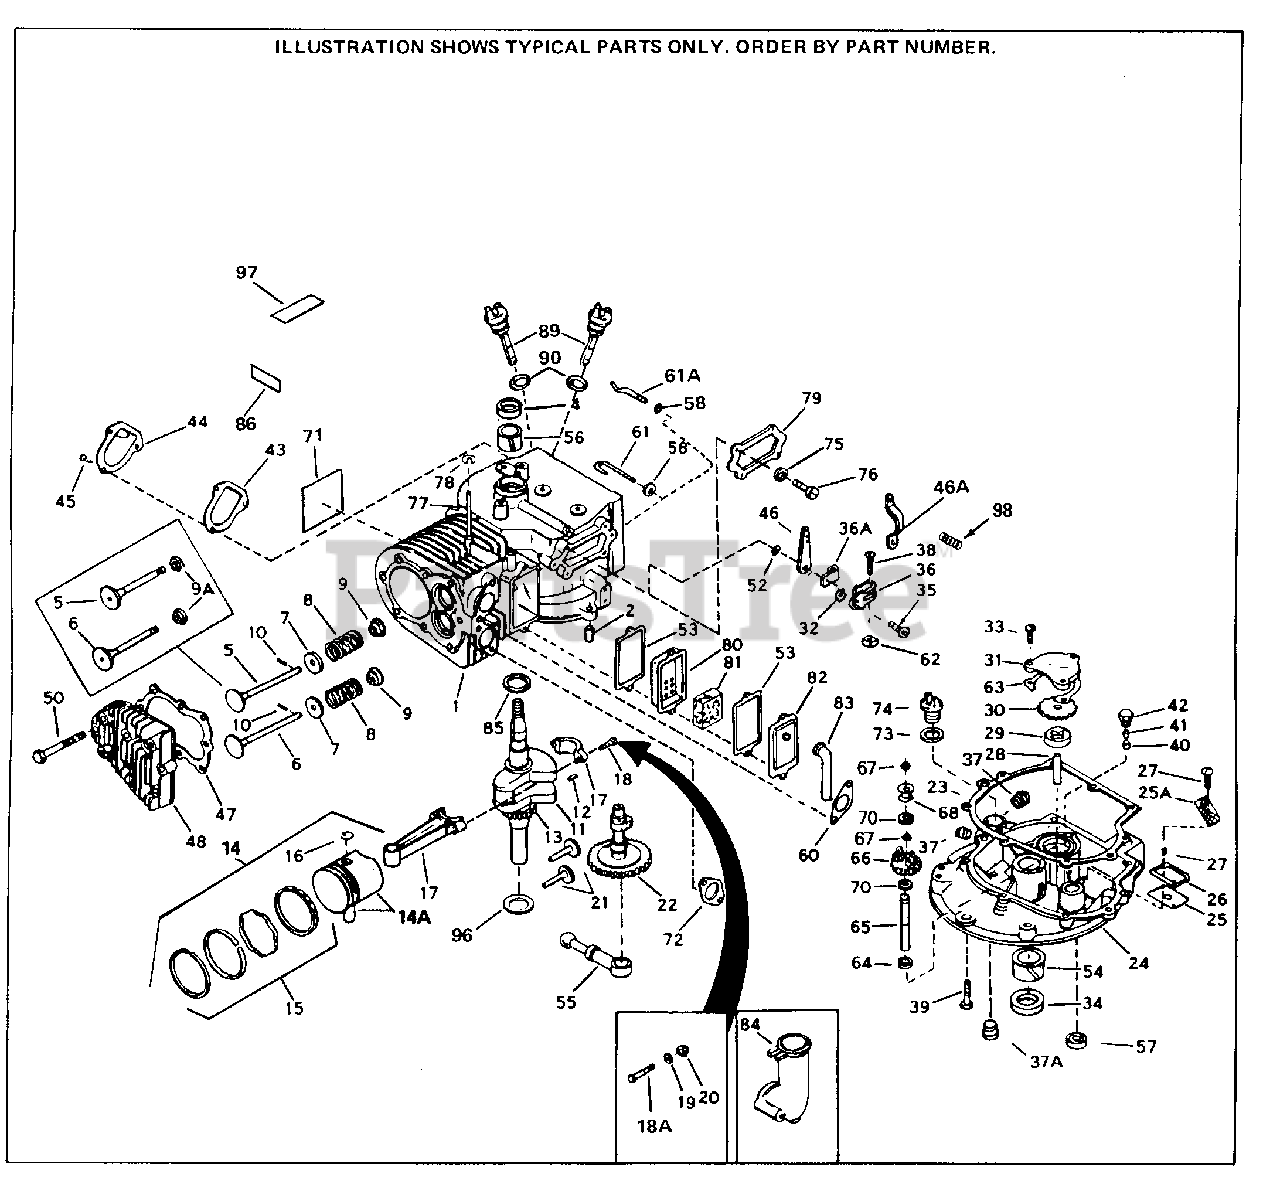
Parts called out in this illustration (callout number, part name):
1	"Cylinder (Incl. 2,4,5,9A,43,44,45,86) (2-5/8")
2	Dowel Pin
4	Seal, Oil
5	Exhaust Valve (Std.)(Incl. 151)
5	Exhaust Valve (1/32" OS) (Incl. 151)
6	Exhaust Valve (Std) (Incl. 9A)
6	Exhaust Valve (1/32" OS) (Incl. 9A)
7	Valve Spring Cap
8	Valve Spring
9	Cap, Lower valve spring (1/32" OS)
9	Cap, Lower valve spring
10	Pin, Valve spring retaining
11	Crankshaft
12	Pin, Crankshaft gear only)
13	Crankshaft Gear Early production only
14	Piston, Pin & Ring Set (Std) 2-5/8"Bo re
14	Piston, Pin & Ring Set (.010" OS)
14	Piston, Pin & Ring Set (.020" OS)
14A	Piston & Pin Ass'y. (Std)(Incl. 16) 2 -5/8"
14A	Piston & Pin Ass'y. (.010" OS) Incl. 16
14A	Piston & Pin Ass'y. (.020" OS) Incl. 16
15	Ring Set (Std) (2-5/8" Bore)
15	Ring Set (.010" OS)
15	Ring Set (.020" OS)
16	Piston Pin Retaining Ring
17	Rod Assy., Connecting (Incl. 18)
18	Bolt, Connecting rod (2 pcs.)
18A	Connecting Rod Bolt Early prod. on V6 0/VH60
18A	Connecting Rod Bolt Early prod. on V5 0/VH50
19	Washer duction)
20	Connecting Rod Bolt Nut Early product ion
21	Lifter, Valve
22	Camshaft (No Compression Release)
22	Camshaft (MCR)
23	Gasket, Mounting flange
24	Mtg.Flange Ass'y. Incl. 34, 37, 54, 6 5 & 70
25	Screen, Oil filter
25A	Screen, Oil filter (Use as required)
26	Retainer, Oil filter screen
27	Screw, 8-32 x 5/16" (Use as required)
28	Dowel Pin
29	Gear, Oil pump
30	Gear, Oil pump drive
31	Cover, Oil pump
33	Screw, 10-32 x 3/4"
34	Oil Seal
37	Oil Drain Plug (Sq. hd., 1/4-18)uired )
37A	Oil Drain Plug (Sq. hd., 1/4-18)quire d)
39	Screw, 1/4-20 x 1-1/4"
40	Plunger, Oil relief
41	Spring, Compression
42	Plug, Oil relief
47	Gasket, Cylinder head
53	Valve Cover Gasket
54	Bushing, Crankshaft
56	Bushing, Crankshaft
58	Flat Washer
60	Intake Pipe Gasket
61	Rod, Governor (Incl. 58)
63	Gasket, Shim (.005 thick)
63	Gasket, Shim (.010 thick)
64	Spacer, Governor gear (Incl. 70)
65	Shaft, Mechanical governor
66	Gear Assy., Governor (Incl. 70)
67	Retaining Ring
68	Spool, Governor
70	WASHER
71	Decal, Instruction
72	Gasket, Muffler
85	Washer, Thrust
86	Decal, Model & Serial No.
97	Decal, Name
